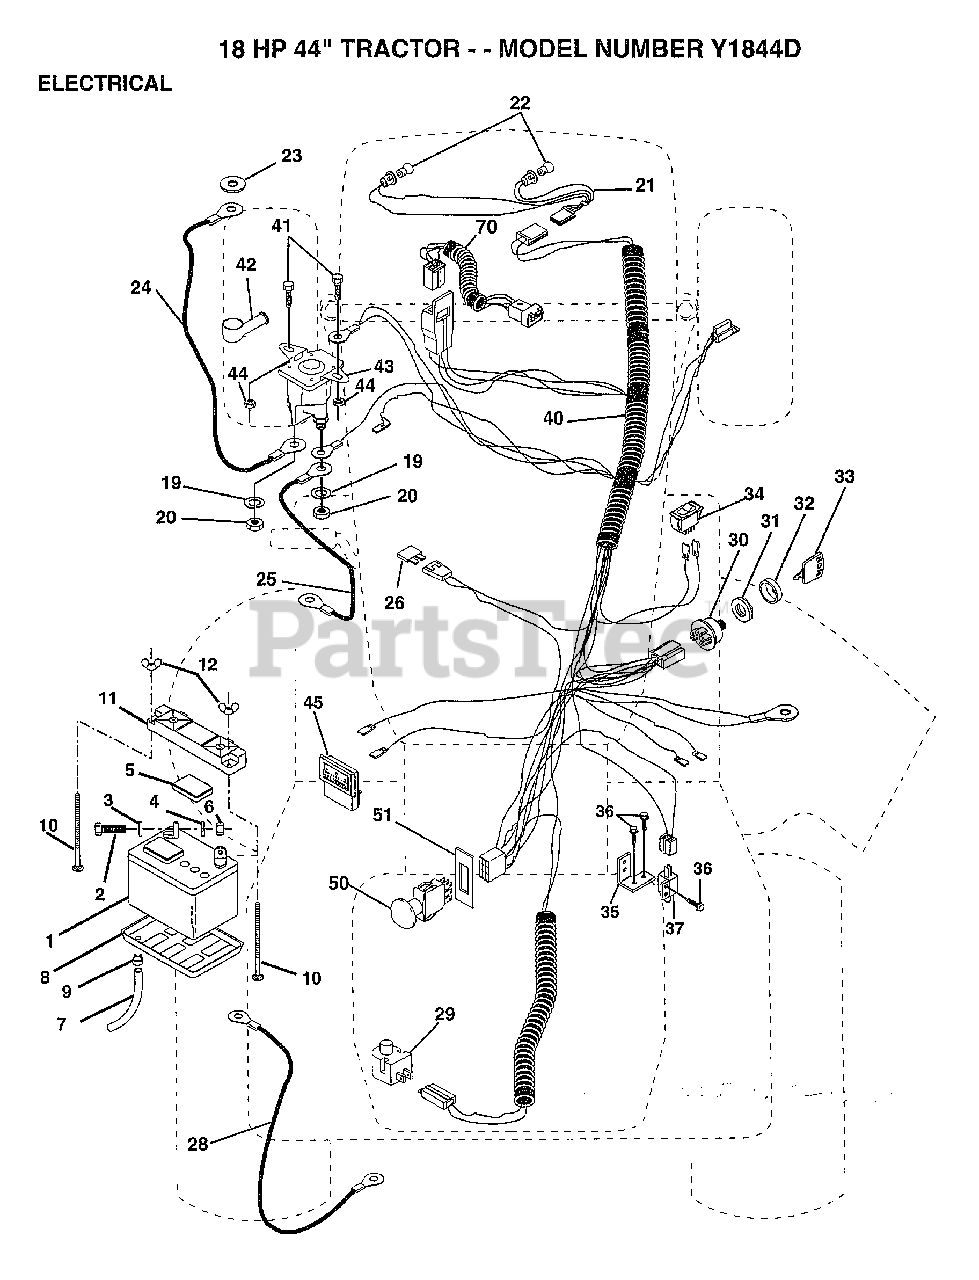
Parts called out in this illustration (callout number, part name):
2	BOLT LT
3	WASHER
4	LOCKWASHER
5	"CAP,BATTERY "
7	"DRAIN TU T, BATT"
8	"TRAY T, BATTERY"
9	HOSE CLAMP T
10	BOLT
20	NUT
21	"HARNESS,LIGHT SOC"
22	HEADLAMP BULB
23	LOCKWASHER
24	"CABLE T, BATTERY"
25	CABLE-BATTERY T
26	FUSE HYT
28	CABLE T
29	SWITCH SEAT
32	COVER KEY SWITCH
33	KEY MLD GEN DELTA
34	SWITCH LT
35	BRACKET LT
36	SCREW
37	SWITCH-INTER. GT
40	HARNESS IGNITION
41	BOLT HXHD FIN
44	NUT HXKEP 1/4X20
45	AMMETER
46	PROTECTION LOOP
51	RING RETAIN PTO
70	HARNESS.ENG.KOHL
